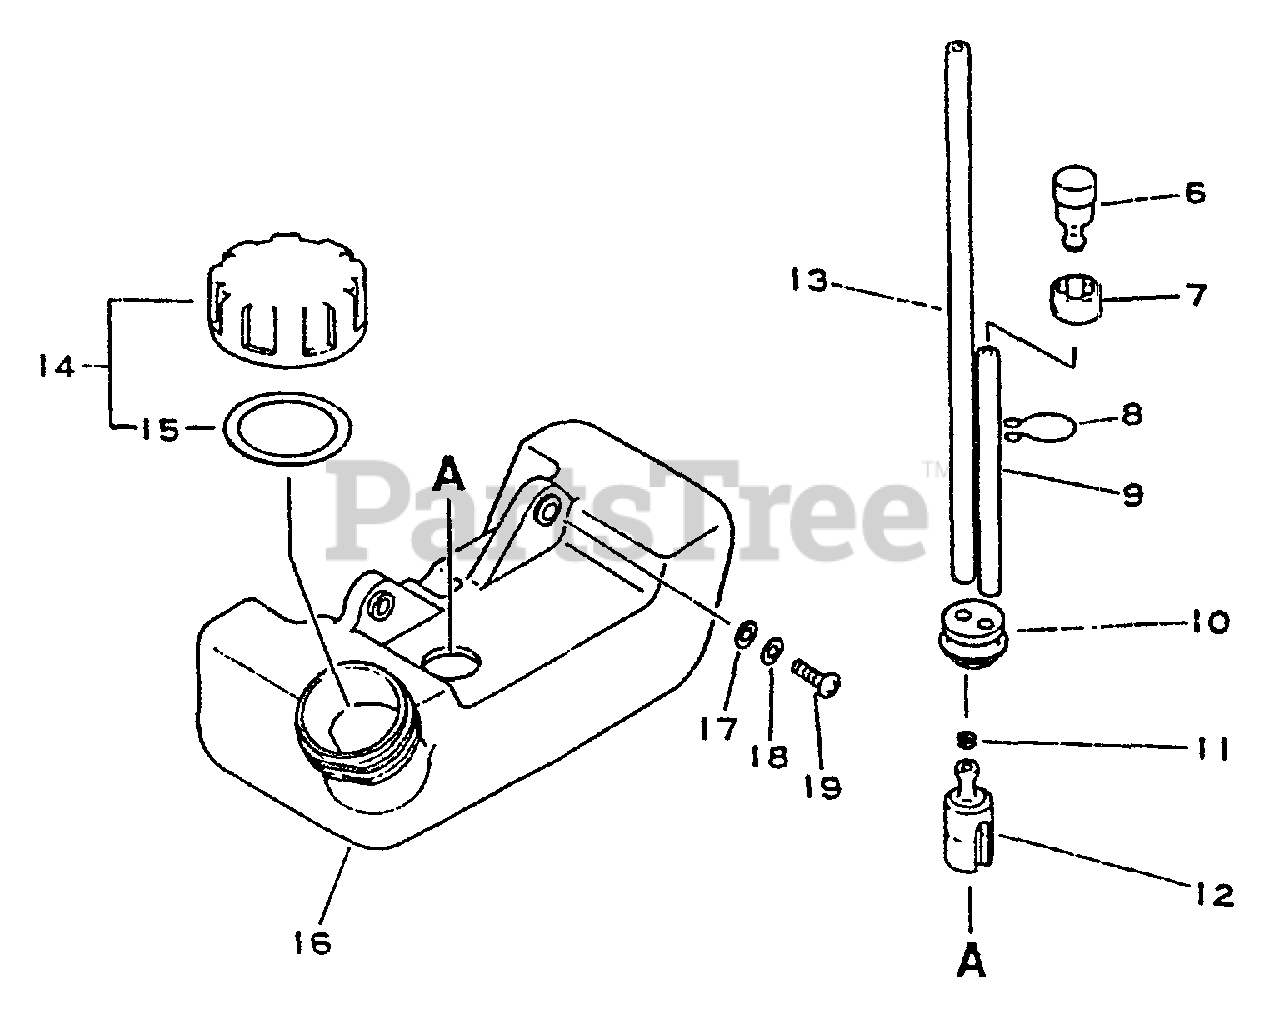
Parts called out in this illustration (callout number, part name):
6	VENT, FUEL TANK
7	COVER, VENT
9	PIPE - 3X6X70 -- CLEAR
10	GROMMET
11	CLIP - 6
12	FILTER, FUEL
13	PIPE - 3X5X180 -- BLACK
14	CAP ASSY
15	GASKET, CAP
16	TANK, FUEL
17	WASHER - 5
18	LOCKWASHER - 5
19	SCREW - 5X16
